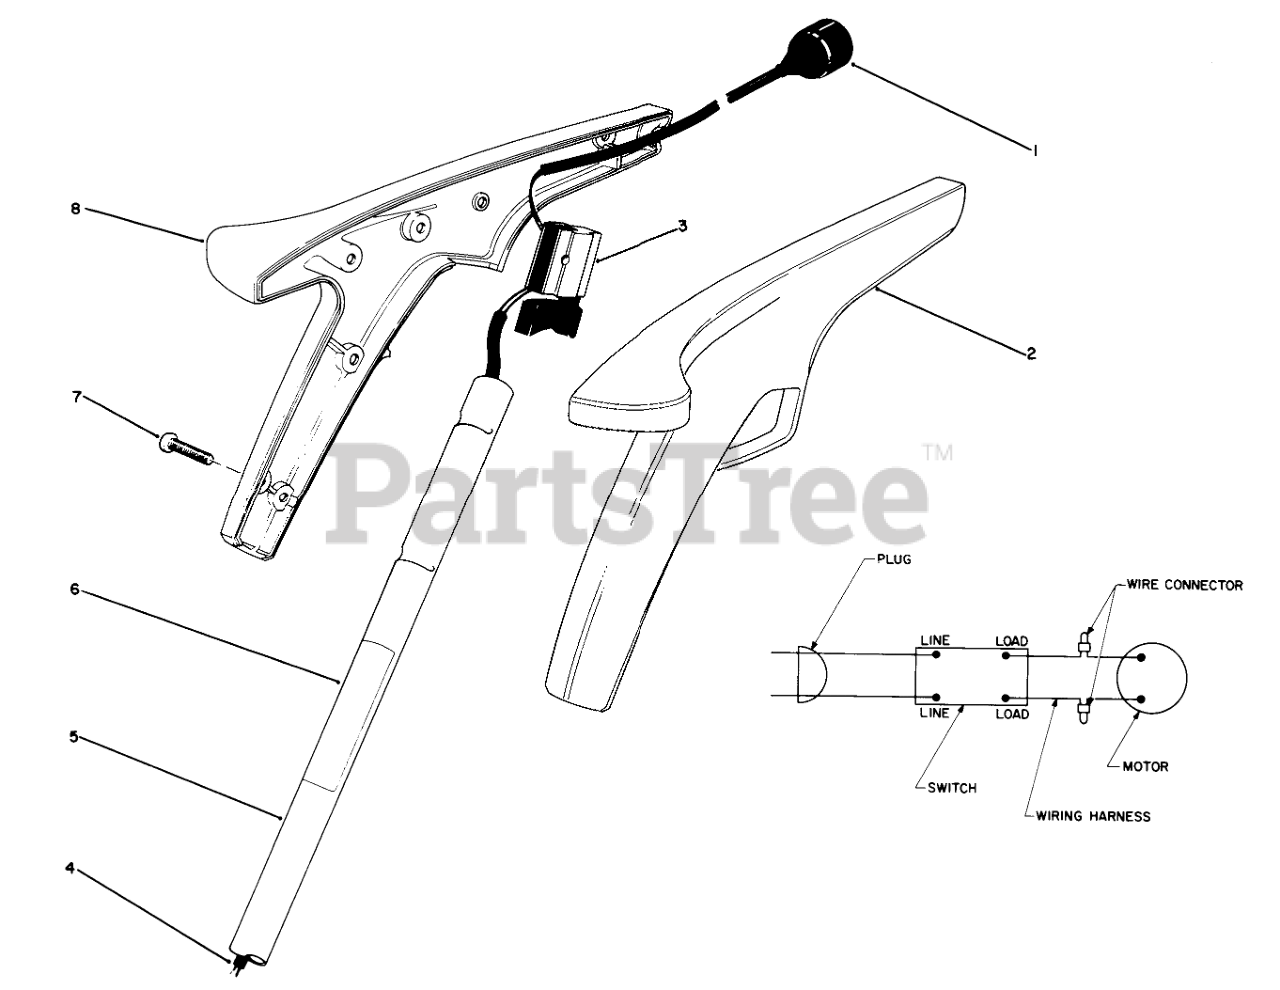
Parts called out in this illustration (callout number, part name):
1	Cord-Power
2	LH HANDLE GRIP, 910
3	SWITCH SINGLE SPEED
4	WIRE HARNESS
5	TUBE EXTENSION
6	REP. SERIAL PLT
7	#8 X .625" PHILPS PAN H
8	Grip-R.H.
